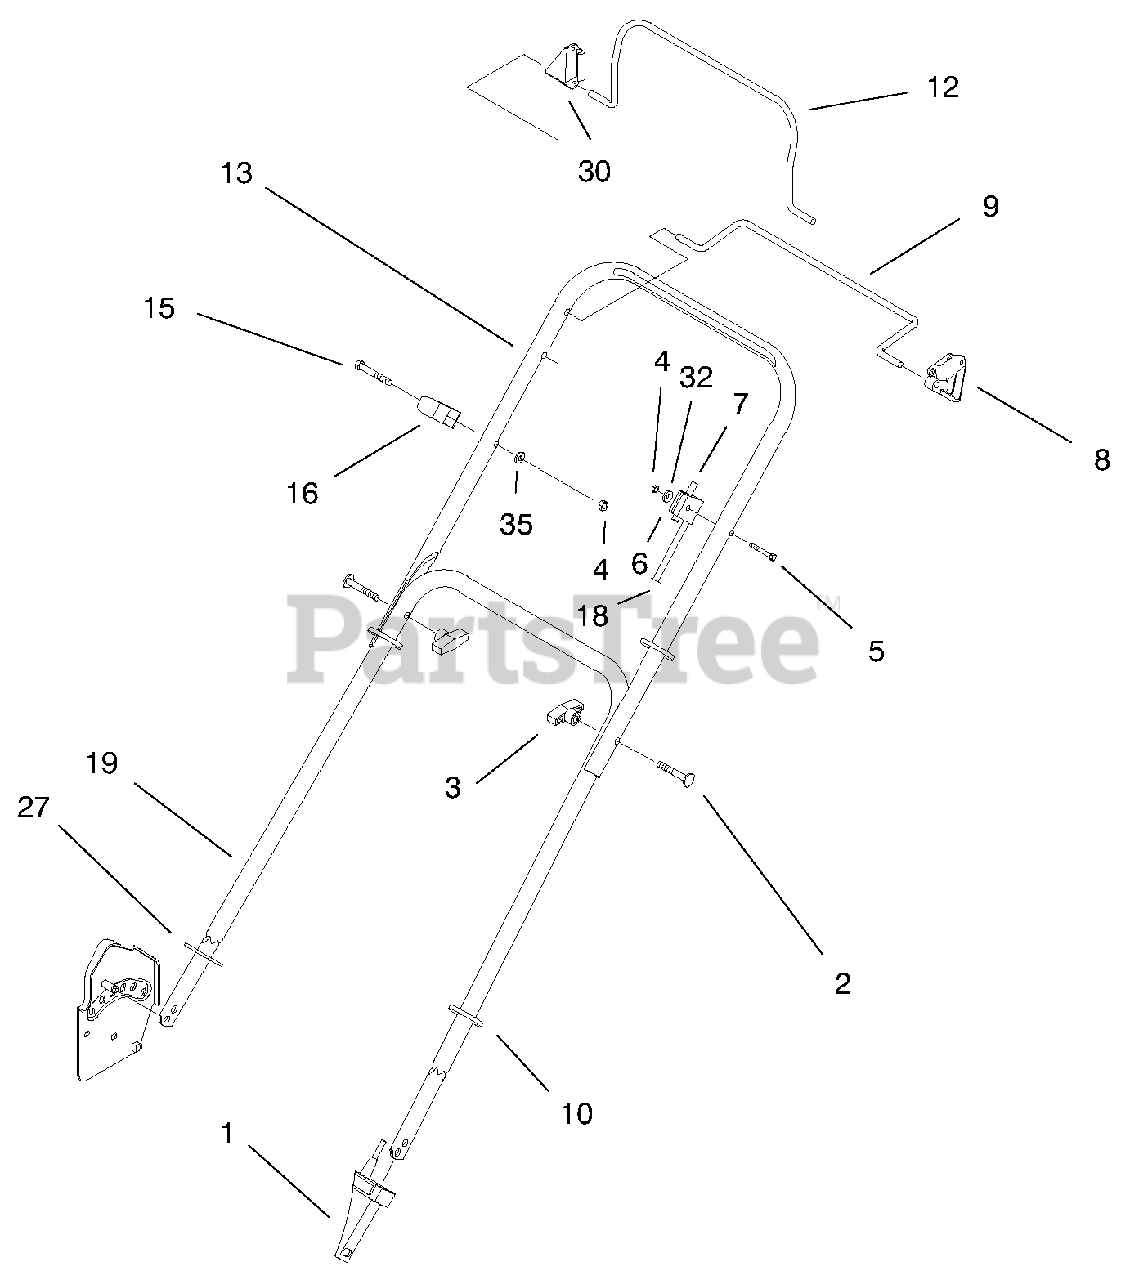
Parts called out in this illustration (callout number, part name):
1	Anchor-Cable
2	Screw-Handle
4	Nut-Lock
5	Screw-Handle
6	Anchor-Cable
7	Cable-Traction
8	Stop-Pivot
9	Bail-Sp Control
10	Tie Strap
12	Bail-Flywheel Brake
13	Handle Section-Upper
15	Bolt-Hex
16	Guide-Rope
18	ASM-Brake Cable
19	Handle Section-Lower
27	Handle-Guard
30	Stop-Bail
32	Washer-Flat
35	Washer
